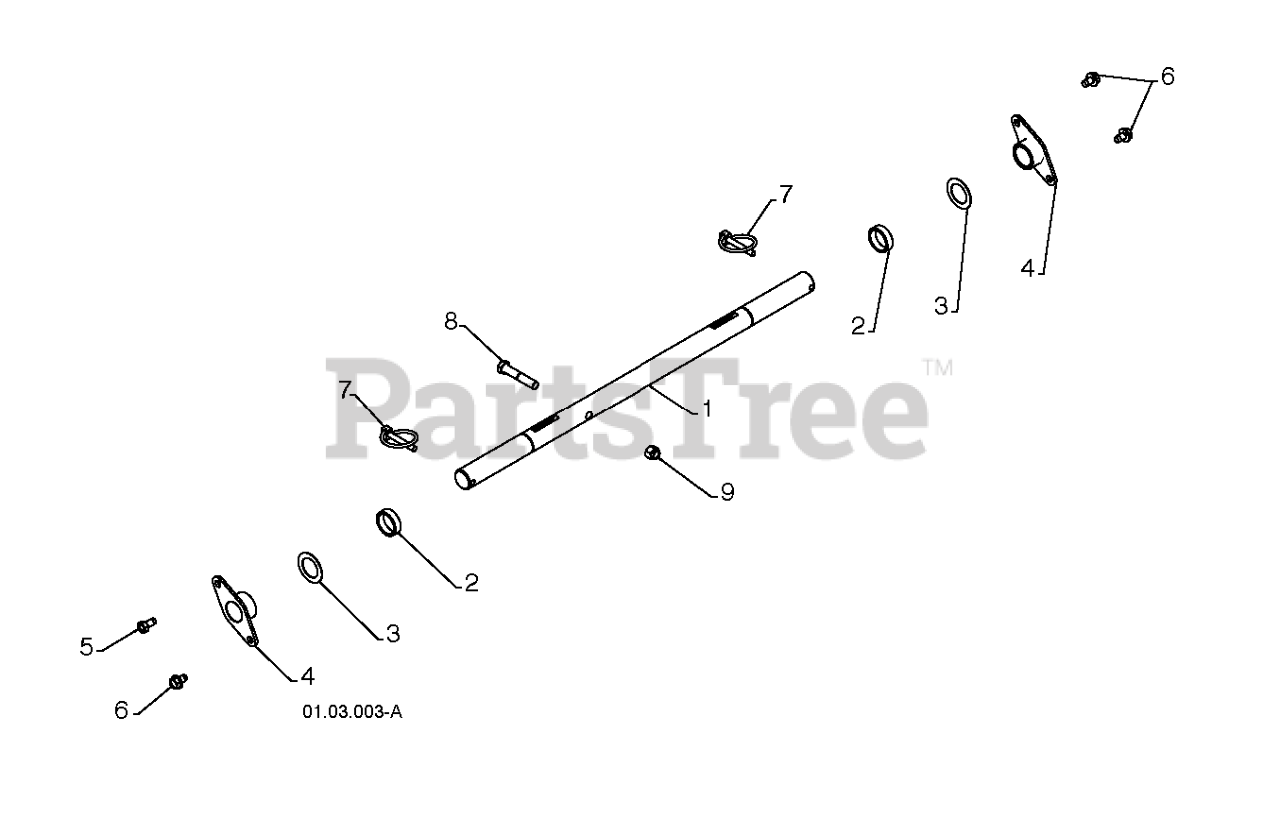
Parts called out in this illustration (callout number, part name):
1	SHAFT.AXLE.POWER.STEERING.HYD
2	SPACER.AXLE.RH
3	WASHER TRUST 1"
4	BEARING, AXLE
6	Screw 5/16-18 x 1/2 Hex, Self Tapping 5/16-18 x 1/2
7	PIN KLIK, 1/4
8	CAP.SCREW.HEX.HD.3/8-16
9	NUT
